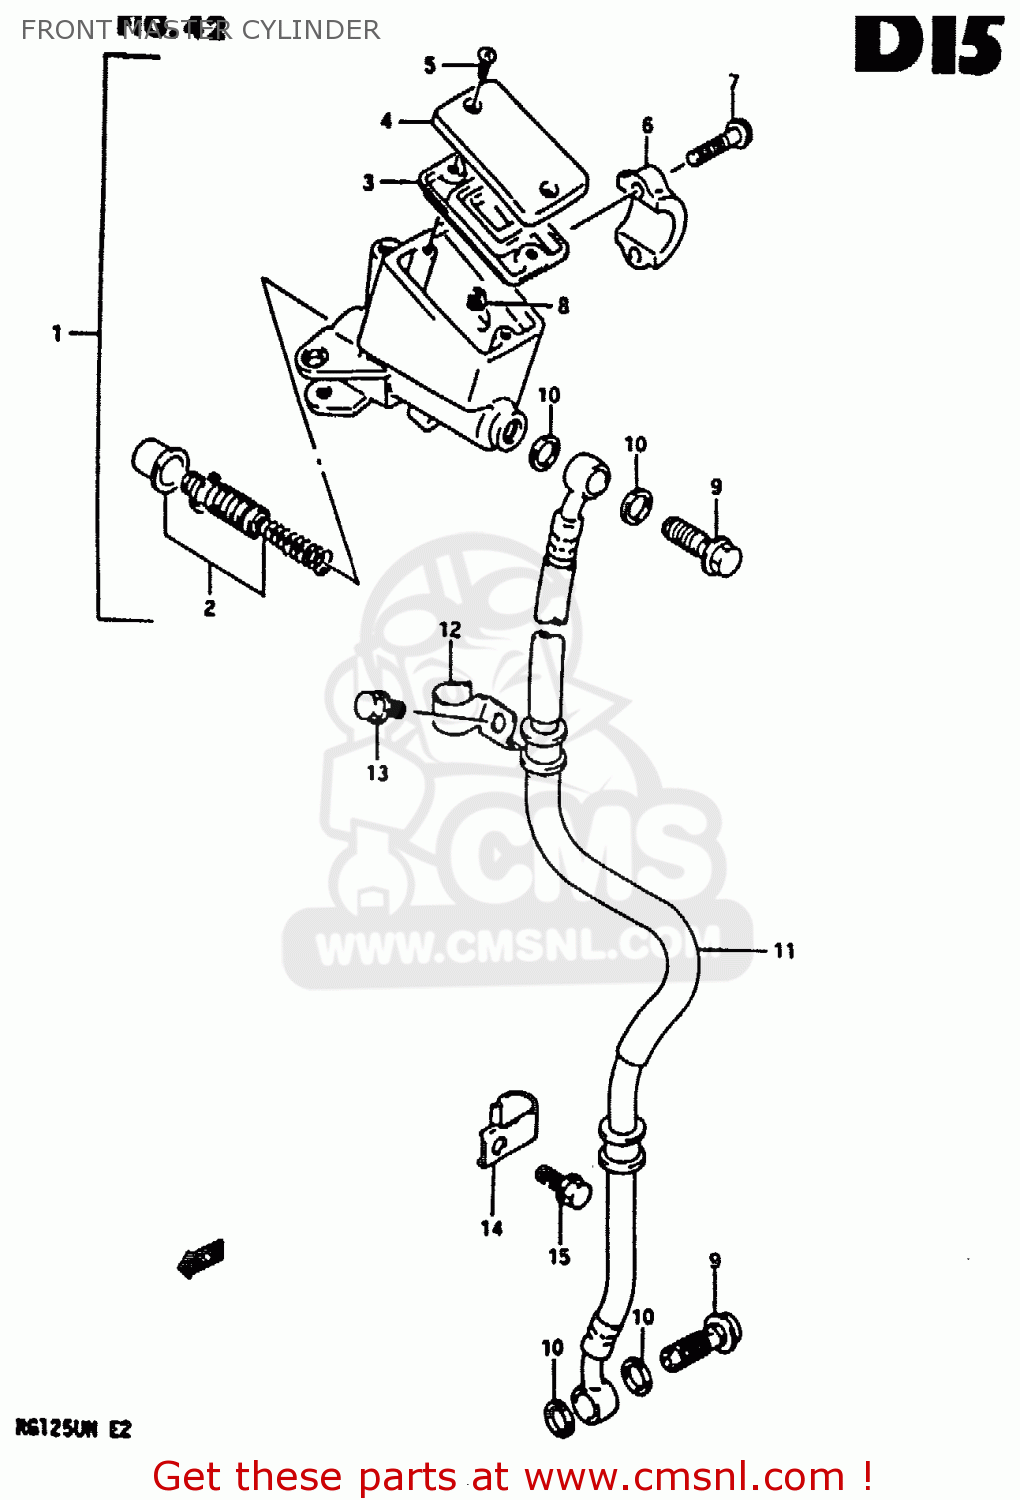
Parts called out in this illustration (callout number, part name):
1	CYLINDER ASSY, FRONT MASTER
2	PISTON/CUP SET
3	DIAPHRAGM
4	CAP
5	SCREW
6	HOLDER
7	BOLT(6X25)
8	PROTECTOR
9	BOLT 10X1.25X24
10	WASHER(10X15X1.5)
11	HOSE,FR BRAKE
12	CLAMP,FR BRAKE HOSE UPR
13	BOLT 6X12
14	CLAMP,FR BRAKE HOSE LWR
15	BOLT
